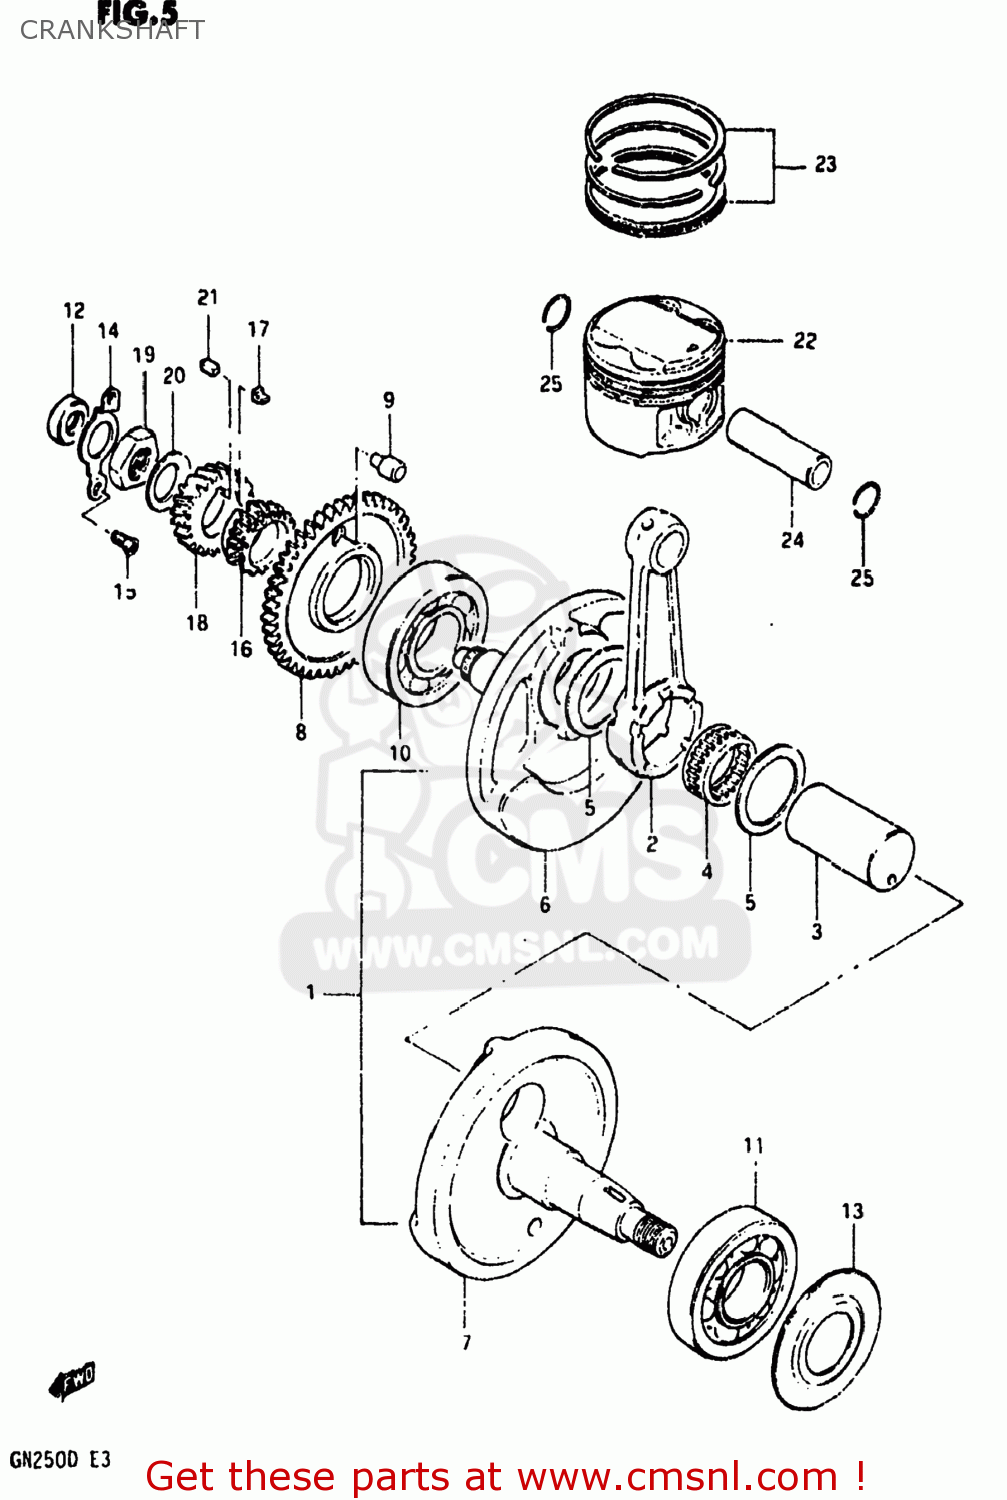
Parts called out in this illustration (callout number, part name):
1	CRANKSHAFT ASSEMBLY
2	CONNECTING ROD
3	PIN,CRANK
4	BEARING
5	WASHER(31X48.5X1)
6	CRANKSHAFT,R
7	CRANKSHAFT,LEFT
8	GEAR,CRANK BALANCER DRIVE
9	PIN
10	BEARING
11	BEARING
12	SEAL,OIL(14X26X6)
13	WASHER,CRANKSHAFT OIL SEALING
14	RETAINER,CRANKSHAFT BEARING,R
15	SCREW
16	SPROCKET,CAM CHAIN DRIVE(NT:21
17	KEY,SPROCKET
18	GEAR,PRIMARY DRIVE NO.21
19	NUT (20MM)
20	WASHER
21	KEY
22	PISTON
23	RING SET,PISTON
24	PIN,PISTON
25	CIRCLIP
